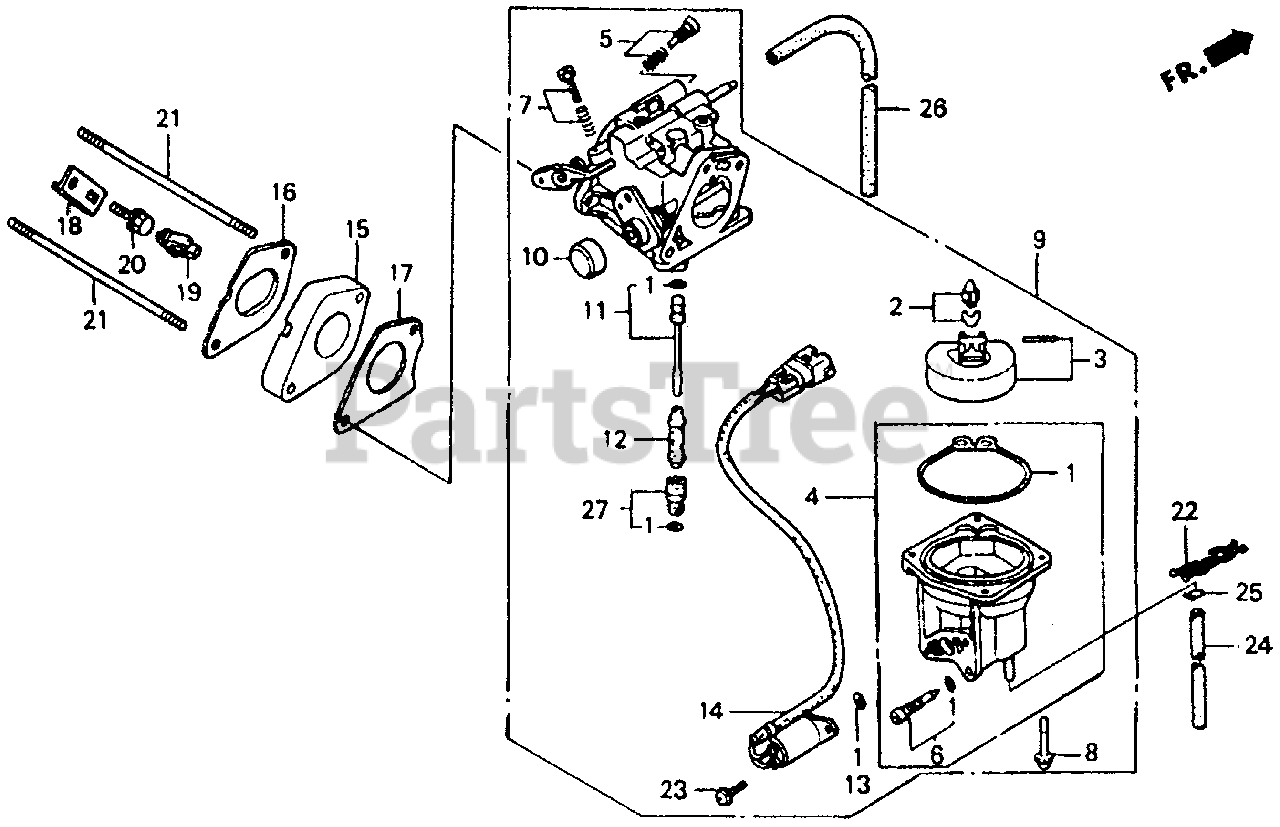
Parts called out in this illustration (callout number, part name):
1	GASKET SET
2	VALVE SET, FLOAT
3	FLOAT SET
4	CHAMBER SET, FLOAT
5	SCREW SET
6	SCREW SET, DRAIN
7	SCREW SET
8	SCREW-WASHER
9	CARBURETOR ASSY. (BG19B A)
10	CAP, CHOKE LEVER DUST
11	JET SET (#48)
12	NOZZLE, MAIN
13	O-RING (5.8X1.9)
14	VALVE ASSY., SOLENOID
15	INSULATOR, CARBURETOR
16	GASKET, INSULATOR
17	GASKET, CARBURETOR
18	BRACKET, HARNESS CLIP
19	CLIP B, AIR TEMPERATURE SWITCH (Honda Code 1610054). WIRE
20	BOLT, FLANGE (6X14)
21	BOLT, STUD (6X113)
22	CLIP, WIRE HARNESS
23	SCREW-WASHER (5X12)
24	BULK HOSE, FUEL (4.5X3000) (Honda Code 5137104). (4.5X380)
25	CLIP, TUBE (B8)
26	BULK HOSE, VACUUM (3.5X1000) (Honda Code 5137153). (3.5X250)
27	JET SET, MAIN (#88)
27	JET SET, MAIN (#92)
27	JET SET, MAIN (#98)
